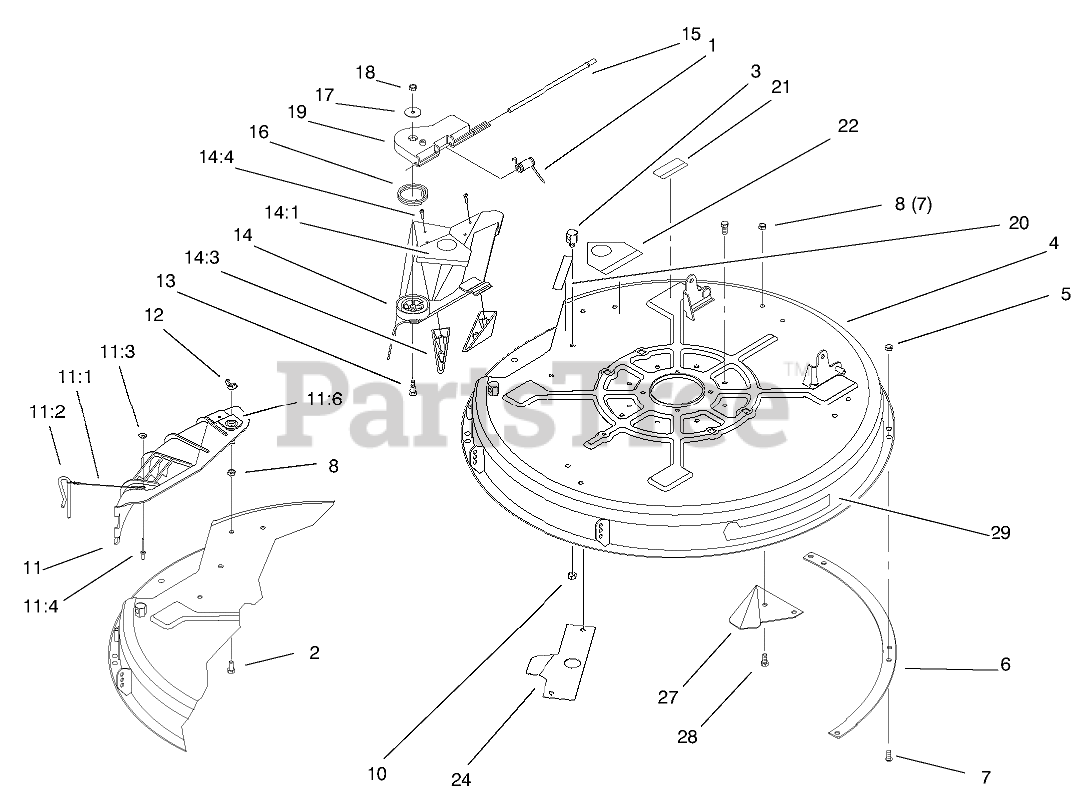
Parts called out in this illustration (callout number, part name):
1	SPRING-TORSION
2	SCREW-HH
3	POST-PIVOT
4	DECK ASM
5	NUT-LOCK, NI
6	RING-DECK
7	SCREW-PPH
8	NUT-LOCK, NI
10	NUT-LOCK, NI
11	DISCHARGE COVER ASM
11:1	LANYARD
11:2	PIN-LOCKING, CHUTE
11:3	WASHER-PLAIN
11:4	RIVET-BLIND
12	NUT-WING
13	BOLT-SHOULDER
14	32 INCH DEFLECTOR ASM
14:1	DECAL-DANGER
14:3	KICKER
14:4	SCREW-PPH
15	ROD-HINGE, DEFLECTOR
16	SPRING-TORSION
17	WASHER-FLAT
18	NUT-LOCK, NI
19	PIVOT-HINGE, DEFLECTOR
20	DECAL-DANGER
21	DECAL-WARNING
22	DECAL-DANGER
24	RAMP-DEFLECTOR
28	SCREW-HH
29	DECAL - RECYCLER 32"
